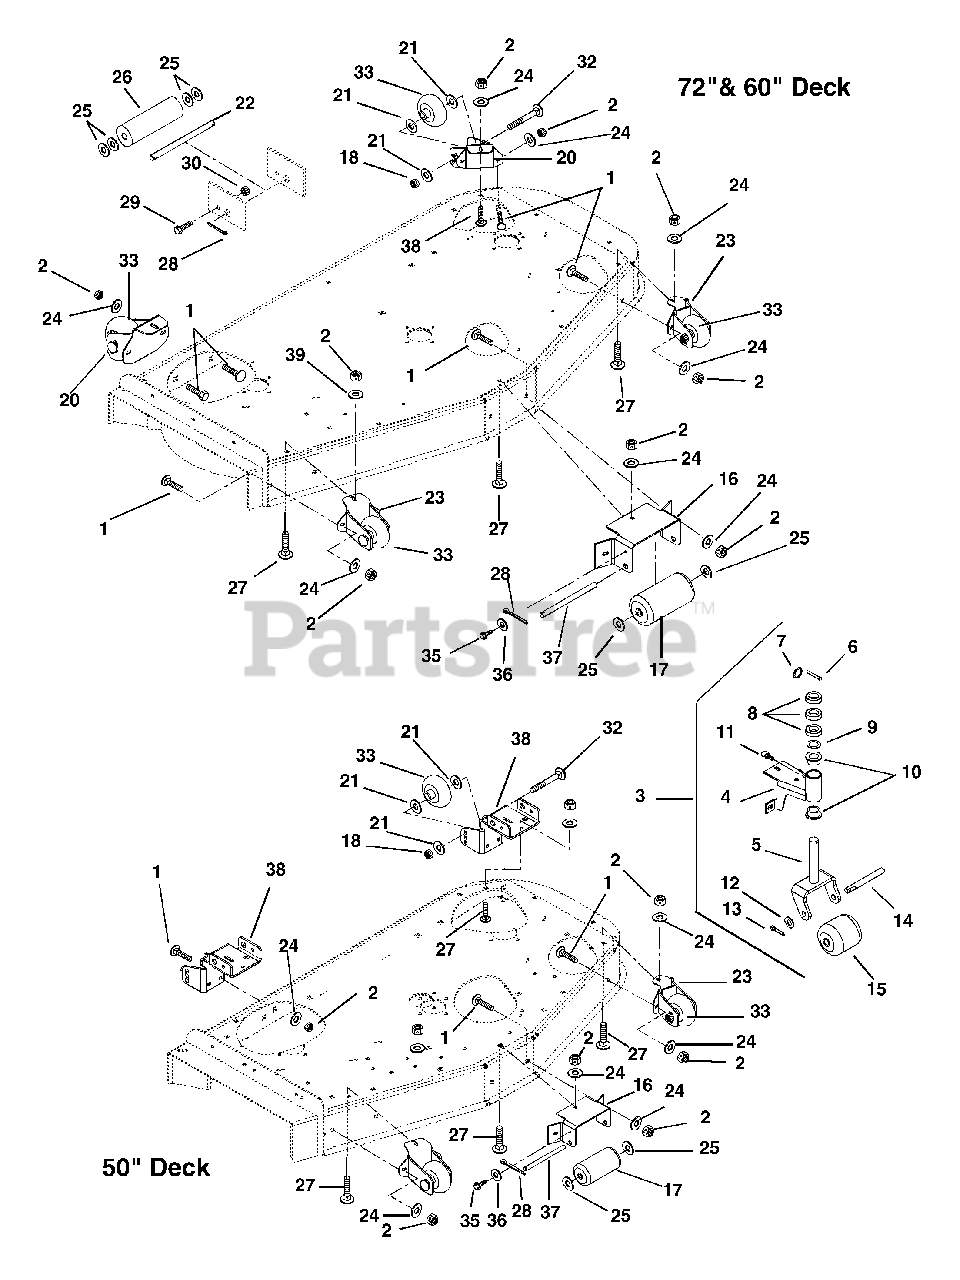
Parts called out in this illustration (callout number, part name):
1	Bolt-Round Head Square Neck .38 - 16 x 1.00 Grade 5
2	Nut-Locking-Nylon .38 - 16
3	Assembly, Roller Bracket
3	Assembly, Roller Bracket-Left Front
4	Weldment-Roller Bracket
4	Weldment-Roller Bracket-Left Front
5	Weldment-Roller Fork
6	Pin-Clevis .19 x 2.00
7	Kickout Ring
8	Bushing-Sleeve 1.04 x 1.75 x .500
9	Washer-Hardened Thrust 1.00 x 1.55 x .03
10	Bushing-Flange 1.020 x 1.385 x .75 x 1.75
11	Fitting-Lube .25 - 28 Taper
12	Washer-Flat Steel .656 x 1.31 x .095
13	Pin-Cotter .25 x 1.00
14	Shaft, Castor
16	Bracket, Anti-Scalp Roller
18	Nut-Locking-Nylon .50 - 13
19	Bolt-Hex .38 - 16 x 1.00 Grade 5
20	Weldment-Wheel Support Left Hand
20	Weldment-Wheel Support Right Hand
21	Washer-Flat-Steel .531 x 1.06 x .095
22	Shaft, Center Roller
23	Weldment-Left Front Roller Bracket
23	Weldment-Right Front Roller Bracket
23	Weldment-Wheel Support Left Hand
23	Weldment-Wheel Support Right Hand
24	Washer-Flat-Steel .406 x .812 x .065
25	Washer-Flat-Steel .656 x 1.31 x .095
26	Roller, Gage
27	Bolt-Round Head Square Neck .38 - 16 x 1.25 Grade 5
28	Pin-Cotter .25 x 2.00
29	Bolt-Hex .25 - 20 x .75 Grade 5
30	Nut-Locking-Center .25-20
31	Bolt-Hex .31-18 x 1.00 Grade 2
32	Bolt-Round Head Square Neck .50-13 x 5.00 Grade 2
33	Wheel, 3 x 5
35	Screw-Self Tapping .25-20 x .50 x Hex Washer Head
36	Washer-Flat-Steel
38	Bracket, Rear Anti Scalp Roller
